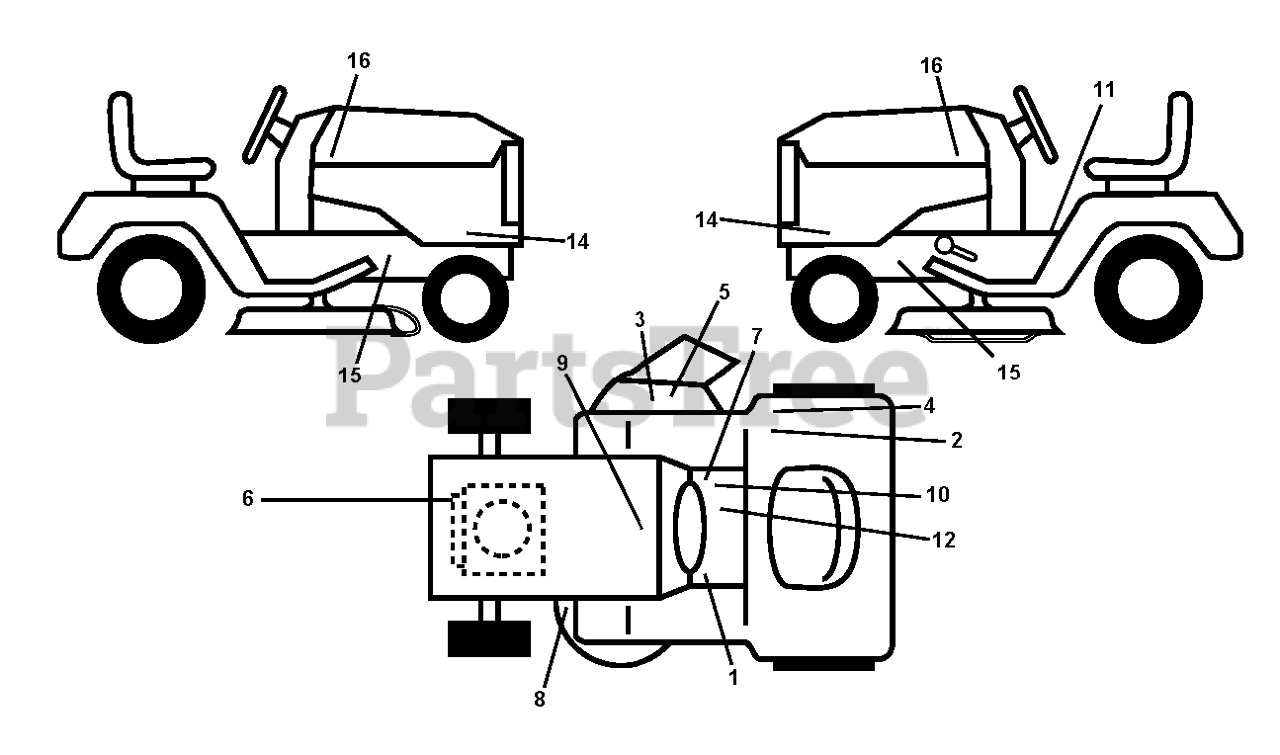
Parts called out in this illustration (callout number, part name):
1	DECAL
2	DECAL
3	DECAL.INTERNATIONL.CUTFINGER
4	DECAL 80 DBA
5	DECAL, DEFLECT WARNING
6	DECAL
7	DECAL PARK BRAKE
8	DECAL V BELT SCHEMATIC
9	DECAL BTRY SYMBOLS
10	DECAL
11	LABEL
16	DECAL.HOOD.LOGO.ORANGE.HUSQVAR
